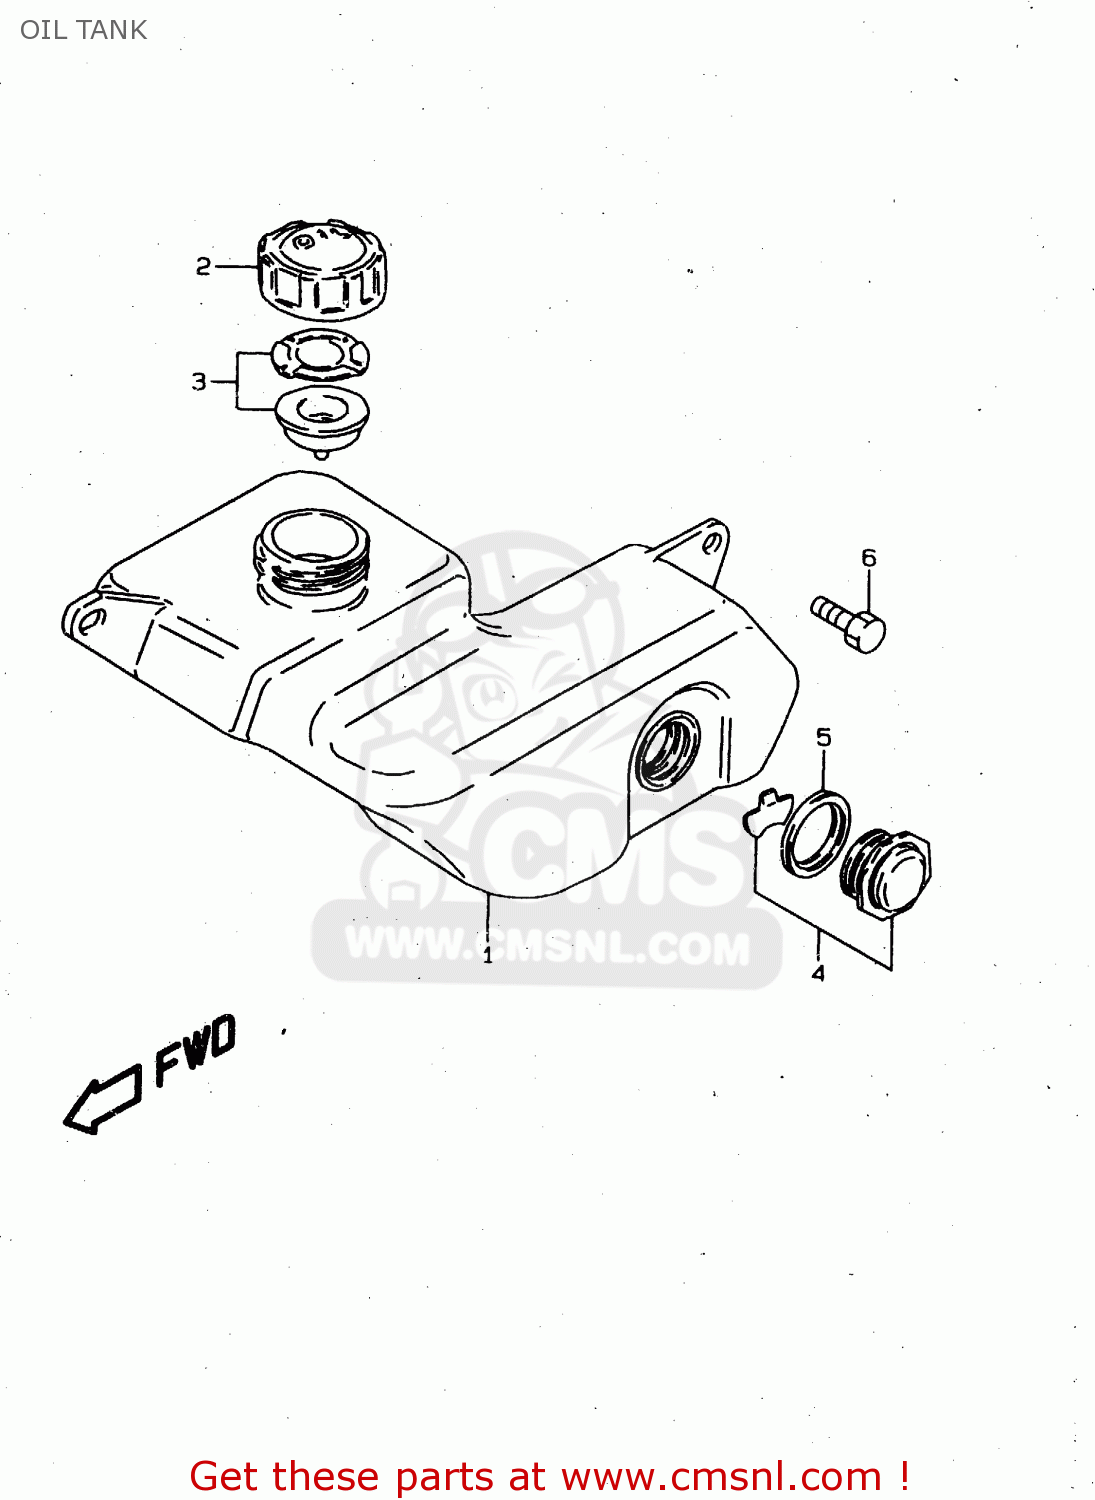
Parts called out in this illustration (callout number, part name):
1	TANK,OIL
2	CAP,OIL TANK
3	GASKET SET (NAS)
4	LENS SET,OIL LEVEL
5	GASKET (NAS)
6	BOLT(6X16)
